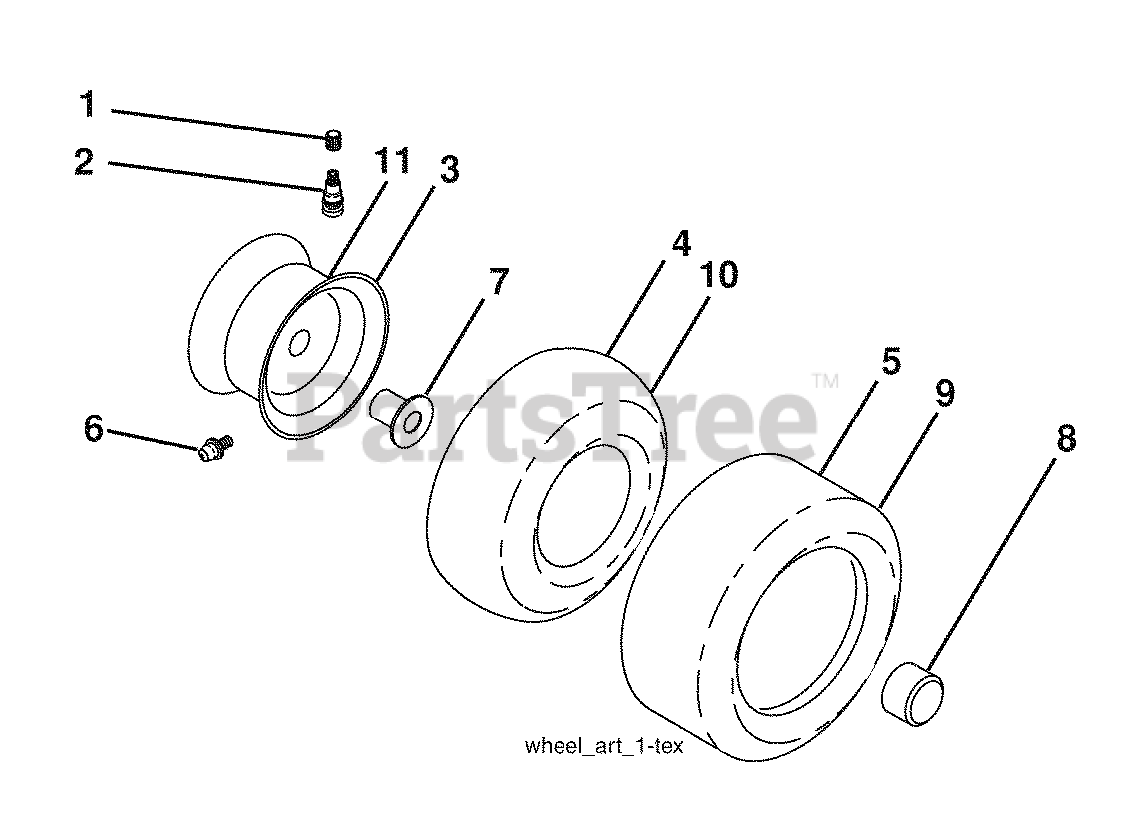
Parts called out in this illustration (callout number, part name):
2	VALVE STEM LT
3	RIM ASM 6" FRONT SILVER
4	TUBE.5.3/4.5/6
5	TIRE.15X6-6.TURF.MASTER.FRONT
6	FITTING LT
7	BEARING T
8	CAP, AXLE BLK
9	TIRE.20X10-8.TURF.MASTER.REAR
10	TUBE
11	RIM ASM 8" REAR SILVER
